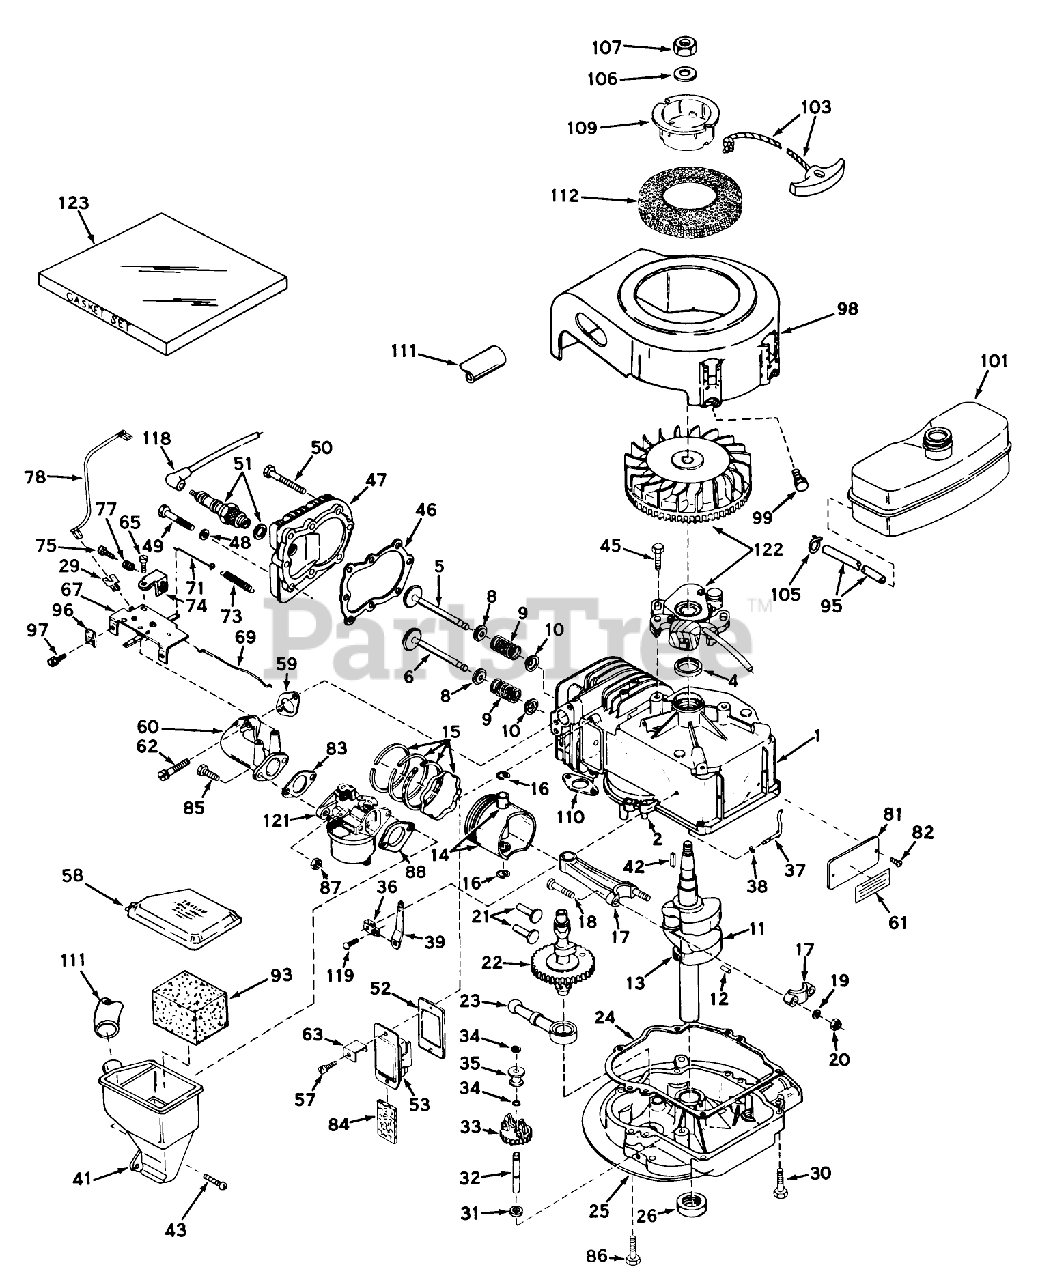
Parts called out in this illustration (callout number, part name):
1	Cylinder Assy. (Incl. Ref. 2 4)
2	Pin-Dowel
4	OIL SEAL
5	Valve, Intake (Incl. Ref. #38, 39 40) (Std.)
5	Valve, Intake(1/32"overs.)(Incl. Ref. 8, 9 10)
6	Valve, Exhaust (Standard)(Incl. Ref. 8, 9 10)
6	Valve, Exhaust (1/32" Overs.(Incl. Ref. 8, 9 10)
8	Cap-Upper Valve Spring
9	Spring-Valve
10	Cap-Valve, Spring
11	Crankshaft Assy. (Incl. Ref. 12 13)(Model LAV35-40455H)
12	Pin, Groove
13	Gear, Crankshaft
14	Piston Pin Assy. (Incl. 2 of No. 16)(Standard)
14	Piston Pin Assy. (Incl. 2 of No. 16)(.010 oversize)
14	53020 ADN. TO 28594
15	Piston Ring Set Std.
15	Piston Ring Set .010 O.S.
15	Piston Ring Set .020 O.S.
16	Ring-Retaining, Piston Pin
17	Rod Assy., Connecting (Incl. Ref. #17)
18	Bolt, Connecting
19	Washer
20	LOCKNUT
21	Lifter-Valve
22	Camshaft
23	Oil Pump ASM
24	Gasket, Mounting
25	Flange Assy., Mounting (Incl. #26 32)
26	Seal Oil
29	Terminal
30	Screw (1/4-20 x 1-1/4)
31	Washer-Flat
32	Shaft-Governor
33	Governor Gear ASM
34	Ring-Retaining
35	Spool-Governor
36	Clamp-Lever, Governor
37	Rod, Governor (Incl. No. 36)
38	Washer-Flat
39	Governor Lever
41	Body, Air Cleaner
42	Key Flywheel
43	Screw, Fil. Hd. Sems
45	Screw
46	Gasket-Cylinder Head
47	CYLINDER HEAD
48	Washer
49	Screw
50	Screw Hex Hd. Cap
51	SPARK PLUG
52	Gasket Breather
53	Breather Assembly (Incl. Nos. 52 84)
57	Screw
58	Cover, Air Cleaner
59	Gasket, Intake
60	Pipe, Intake
61	480B GIL SNWTHWR O/
62	Screw, Fil. Hd. Sems
63	Retainer Clip
65	Screw (10-24 x 9/16)
67	Control Assy., Speed
69	Link Governor
71	Link-Governor
73	Spring, Governor
74	Brachet, Control
75	Screw, Hex Hd.
77	Spring
78	Wire, Ground
81	IDENTIFICATION PLATE
82	Stud
83	Gasket
84	Element-Breather
86	Screw
87	Nut and Lock Washer (1/4-28)
88	Gasket-Air Cleaner
93	Element, Air Cleaner
95	Line-Fuel (8.62)
96	Conduit
97	Screw (10-32 x 3/8)
98	Housing, Blower
99	Screw (1/4-20x19/32)
101	Tank, Fuel
103	Rope Assy., Starter
105	Clamp-Line, Fuel
106	Washer
107	Hex Nut
109	Pulley Starter
110	Gasket Exhaust
111	Tube, Air Cleaner
112	Screen, Air
118	Cover-Spark Plug
119	Screw
121	Carburetor
122	Magneto
123	Gasket Set (Incl. Items Marked *)
